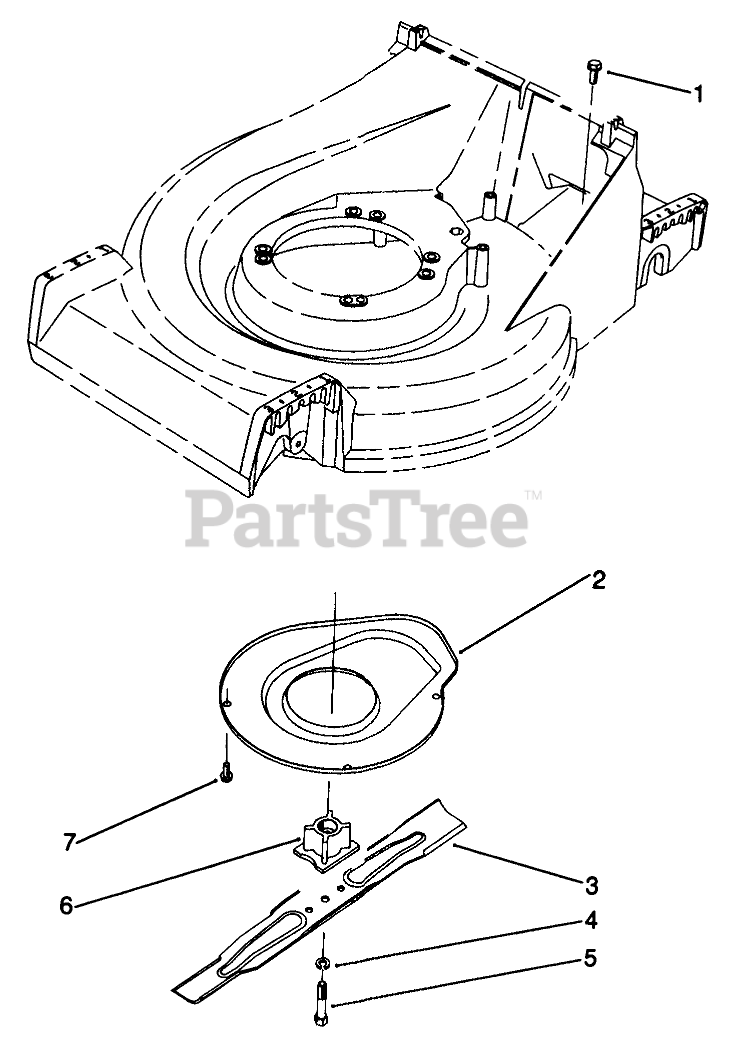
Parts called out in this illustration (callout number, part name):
1	SCREW-HWHTF
2	Cover
3	Key
4	WASHER-LOCK
5	SCREW-BLADE
6	BLADE RETAINER
